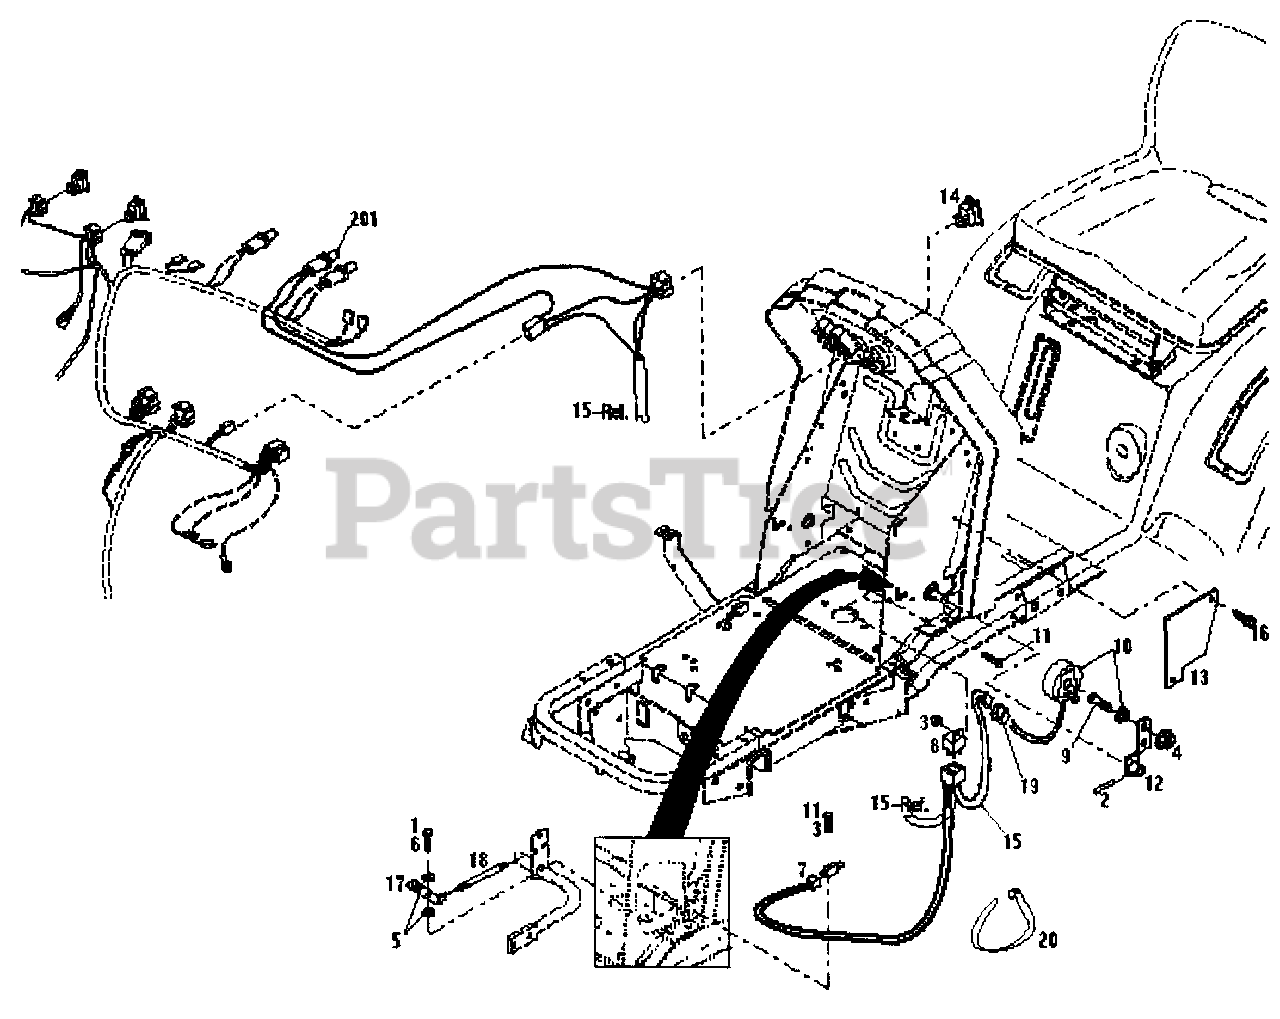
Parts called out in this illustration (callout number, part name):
1	Screw, 1/4-20 x 5/8
2	Drive Pin, 3/16 x 1
4	Whiz Locknut
7	Push-button Switch
8	Speed Control Relay
9	Special Screw
10	Magnet
11	Sems Screw, 10-24 x 5/8
12	Upper Cruise Arm Assembly
13	Cruise Control Plate
14	Cruise Control Switch
15	Cruise Control Harness
16	Thread-Cutting Screw, 5/16-18 x 3/4
17	Lower Cruise Arm Assembly
18	Extension Spring
19	Connector
20	Wire Tie
201	Indicator Light Bulb
